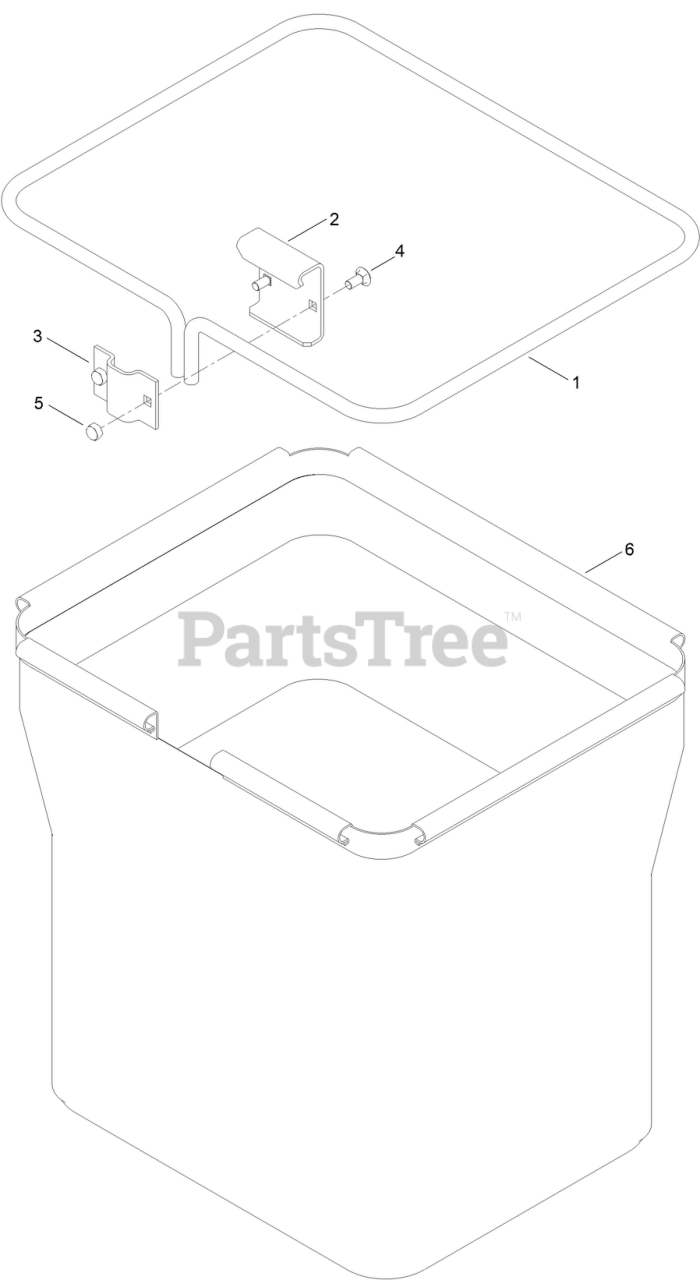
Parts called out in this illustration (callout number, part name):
1	FRAME-BAG
2	HANGER-BAG
4	BOLT-CARR
5	NUT-HEX
6	BAG ASM 20IN DEPTH
